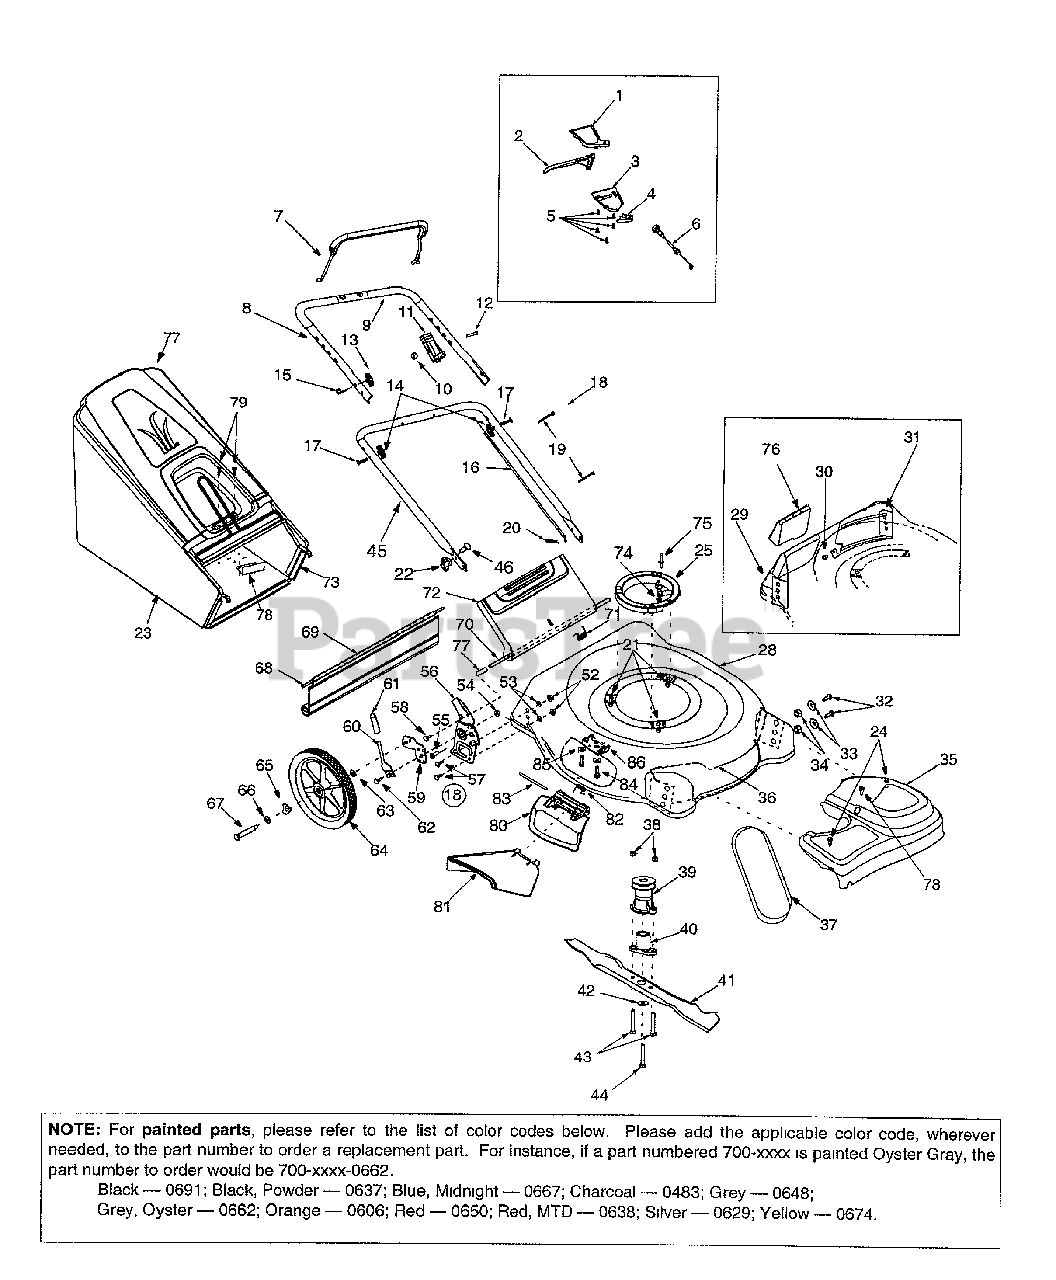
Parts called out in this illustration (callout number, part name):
1	Upper Drive Cover
2	Drive Lever
3	Lower Drive Cover
4	Mounting Cap
5	Screw # 10-16 x .75
6	Drive Cable
9	Foam Grip, 9"
10	Hex Lock Nut, 1/4-20
11	Control Housing
12	Oval C-Sunk Screw 1/4-20 x 1.31
13	Handle Knob
14	Handle Knob
15	Eye Bolt
16	Control Cable, 40.5"
17	Carriage Bolt 5/16-18 x 2.0
18	RH Bracket Ass'y
19	Cable Tie
20	Cotter Pin
21	Self-Tapping Screw
22	Wing Knob
23	Grass Bag
24	Screw # 12 x .457
25	Engine Spacer
30	Screw AB: 1/4-14: .625
32	Hex Screw 3/8-16 x .75
33	Bell Washer.39 x 1.13 x .062
34	Hex Nut 3/8-16
35	Transmission Cover (Black)
38	Hex Nut 1/4-20
39	Drive Pulley
40	Blade Adapter
41	21" Mulching Blade
42	Flat Washer .516 x 1.5 x.1 34
43	Hex Screw 1/4-20 x 1.50
44	Hex Screw 3/8-24 x 2.50
46	Carriage Bolt, 1/4-20 x .75"
52	Hex Lock Nut
53	Bell Washer .39 I.D. x 1.38 O.D.
54	Hex Flange Lock Nut 3/8-16
55	Hex Scr. w/Washer 1/4-14 x .625
57	Hex Bolt 3/8-16 x 1.0"
58	Pan Head Screw
59	RH Pivot Bar
60	Height Adj. Lever
61	Foam Grip
62	Shoulder Scr .500 Dia. x .434
63	Washer .401 x .870 x .063
64	Wheel, 14 x 2 Grey
65	Spring Washer .50 I.D. x 1.0 O.D.
66	Flat Washer .510 x 1.373 x .04
67	Shoulder Screw
68	Wire
69	Rear Trailing Shield
70	Pivot Rod
71	Torsion Spring
74	Hex Nut
75	Screw
77	Hardtop w/ logo
80	Mulching Plug (Hinged)
81	Chute Deflector
82	Torsion Spring
83	Hinge Pin
84	Tapp Scr. 1/4-20 x .500
85	Bell Washer .265 x .75 x .062
